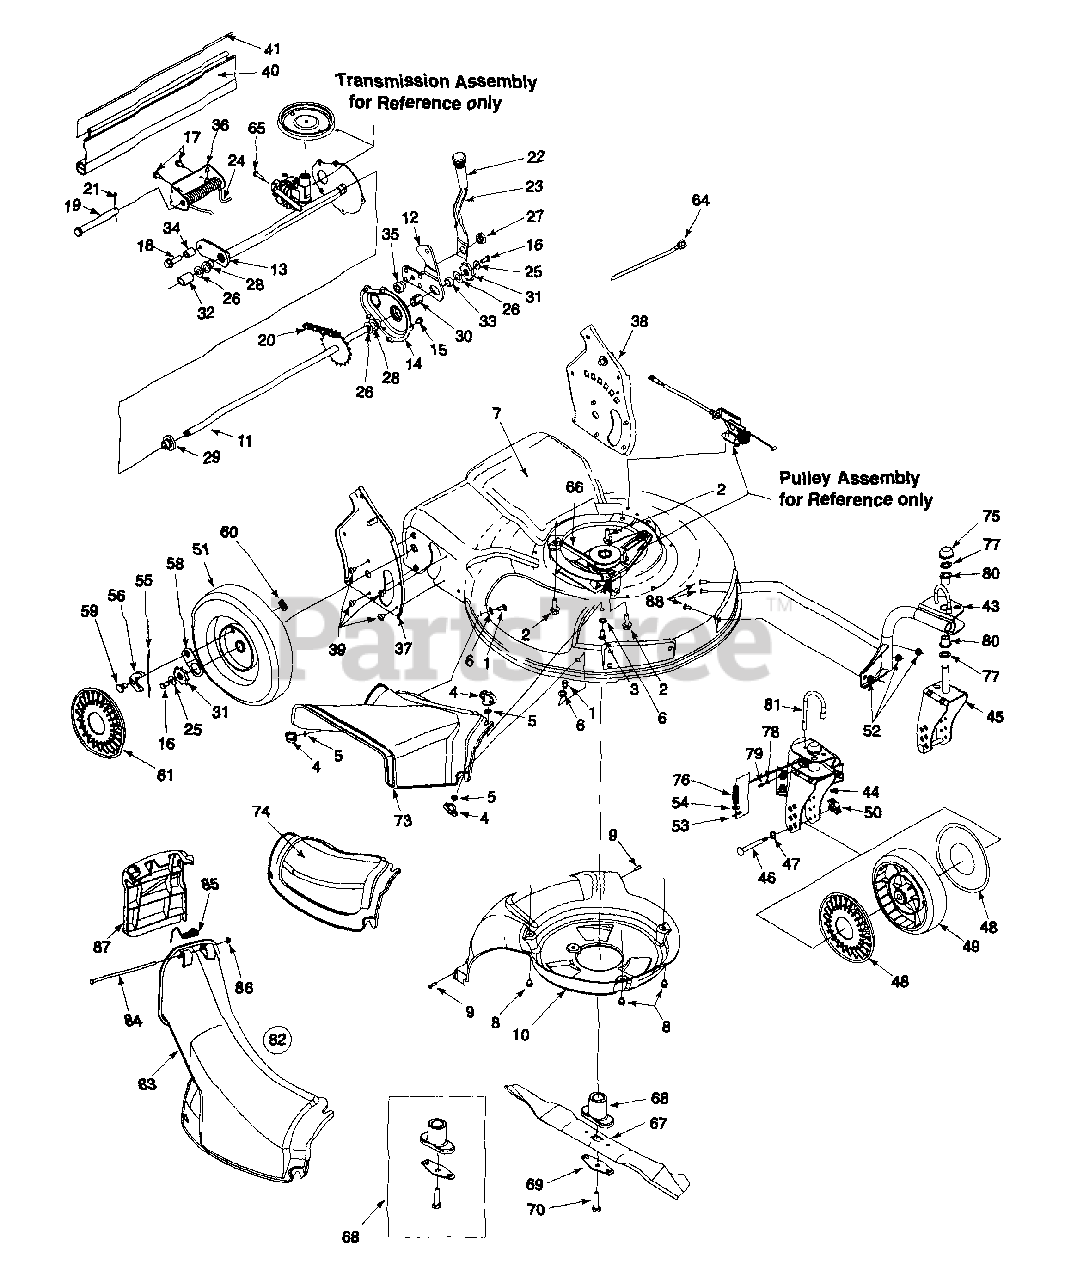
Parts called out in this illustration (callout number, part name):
1	Scr. Carr. 1/4-20 x .62
2	Scr. TT:3/8-18:1.00
3	Carriage Scr. 1/4-20 x .750
4	Wing Nut 1/4-20
5	Nut, Push .25 I.D. x .50 O.D.
6	Wash. Fl. .334 I.D. x .62 x .03
8	Scr. TT. 1/4-20 x .375
9	Scr. HL. 1/2-14 x .750
10	Baffle
11	Rear Axle Assembly
16	Cap Screw HH 1/4-20 x .620
17	Scr. AB 1/4-20 x .625
18	Scr. 3/8 116 x .25
19	Clevis Pin .50 Dia. x 4.82 Lg.
20	Chain-Endls. #48 .500P x 24L
21	Cotter Pin .125 O.D. x .75
23	Spring Lever
24	Torsion Spring
25	Bell Wash. .285 x .75 x .082
26	Fl. Wash. .506 I.D. 3.000 x .
27	Nut Shld. .825 Dia. x .165 Lg.
28	Hx. Flg. Brg. .506 I.D. x .590 L.
29	Hx. Flg. Brg. .506 I.D. x .715 L.
30	Hx. Slv. Brg. .504 I.D. x .830 L.
31	Wheel Rachet
32	Spa. .550 I.D. x /750 O.D.
33	Spa. .51 .D. x .70 O.D. x 38 L.
34	Spa. .385 x .624 x .700
35	Shld. Spa. .385 I.D. X .715 Lg.
40	Trail Shield
41	Trail Shield Wire
46	Caster Axle .374 Dia x 2.50"
47	Wave Washer
48	Hub Cap, Yellow w/hole
49	Wheel 7 x 2 Link
50	Wing Nut 1/4-20
51	Wheel 9 x 2 Link
52	Lock Nut 5/15-18
53	Cotter Pin .072 x .12 Lg.
54	Fl. Wash. .330 x .830 x .060
55	Spring, Ratchet, Plastic
56	Pawl - R.H.
56	Pawl - L.H.
58	Ratchet Pawl Plate
59	Scr. Shld. .340 x .285
60	Top Lock Tab Weld Nut 1/4-20
63	Casing Clamp, Throttle
64	Cable Tie
65	Hex Scr. 5/16-18
66	Belt, 3/8" x 39.24"
67	21" Mulching Blade
68	Blade Adapter
69	Blade Bell Support
70	Hex Bolt 3/8-24 x 2.5" Lg.
73	Side Discharge Chute
74	Mulch Cover
75	Push Cap
76	Compression Spring
77	Fl. Wash. .5/8 I.D. x 1" O.D.
78	Fl. Wash. .203 x .403 x .
79	Fitting - Grease
80	Flange Bearing
81	Locking Pin
82	Chute Ass'y
83	Discharge Chute
84	Pivot Rod
85	Torsion Spring
86	Push Cap
87	Chute Door
88	Carr. Bolt 5/16-18 x .62
